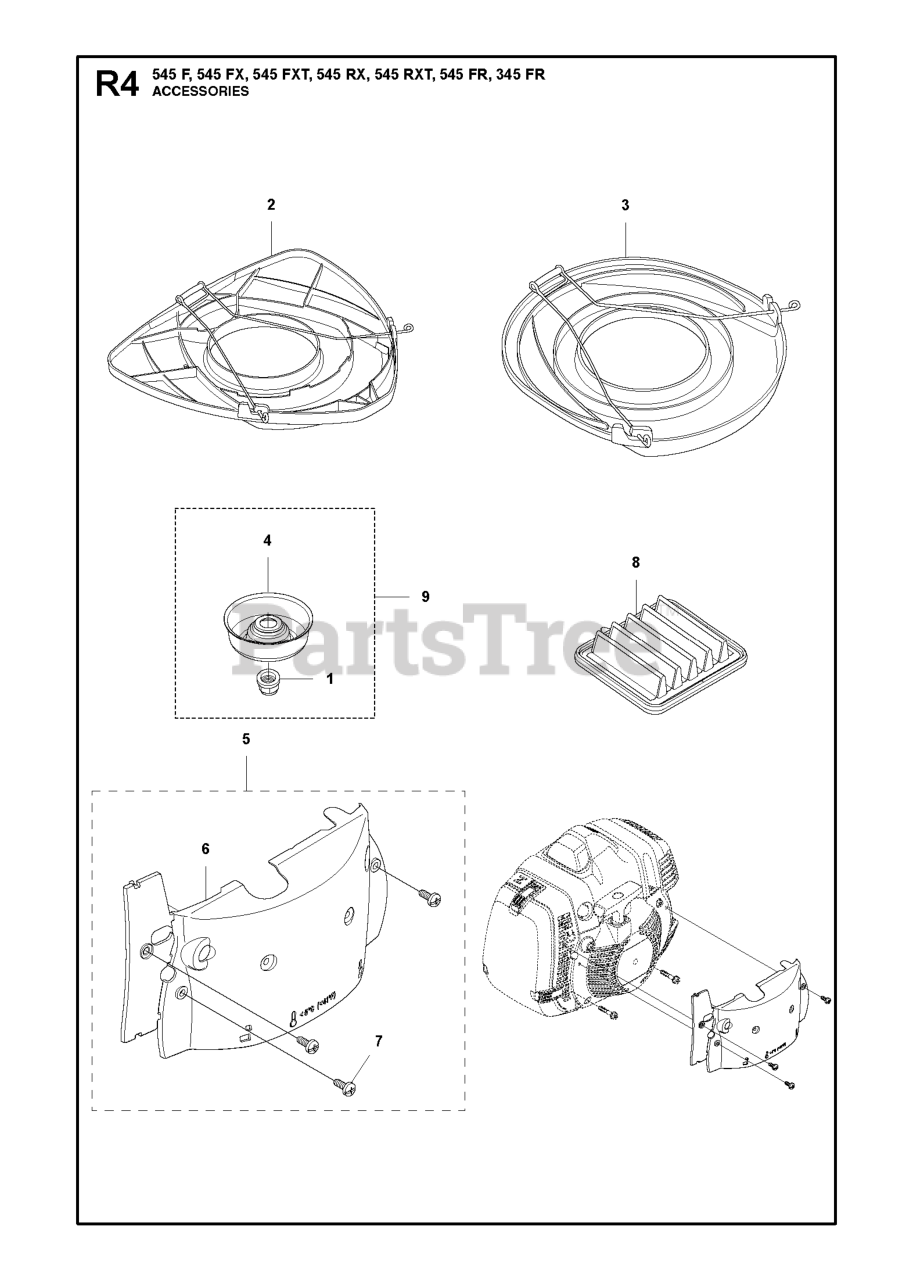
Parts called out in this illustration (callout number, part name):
2	TRANSPORT GUARD
3	BLADE GUARD TRANSPORT
4	SUPPORT CUP
5	WINTER KIT
6	WINTER COVER
8	Filters
